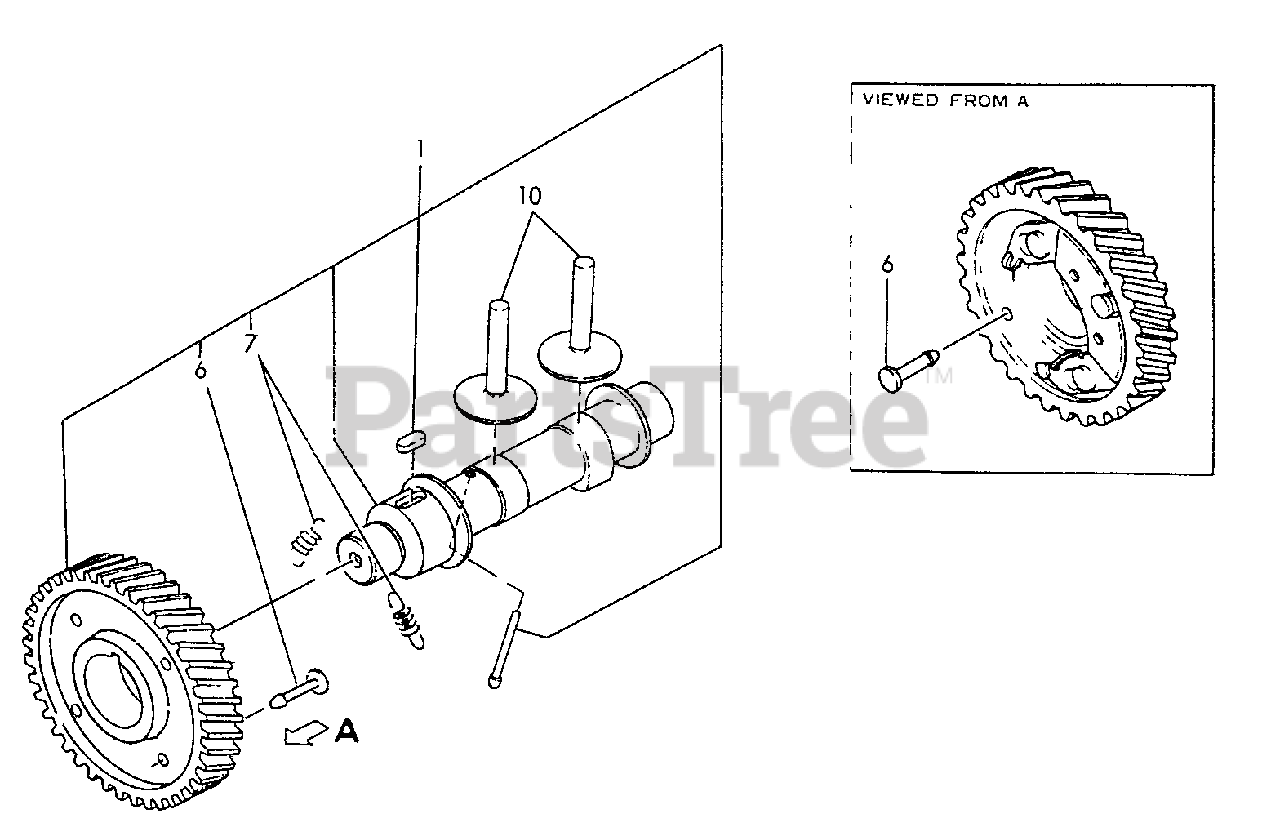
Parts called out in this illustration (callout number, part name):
1	CAMSHAFT ASSY
6	GUIDE PIN
7	SPRING, DECOMP.
10	TAPPET
